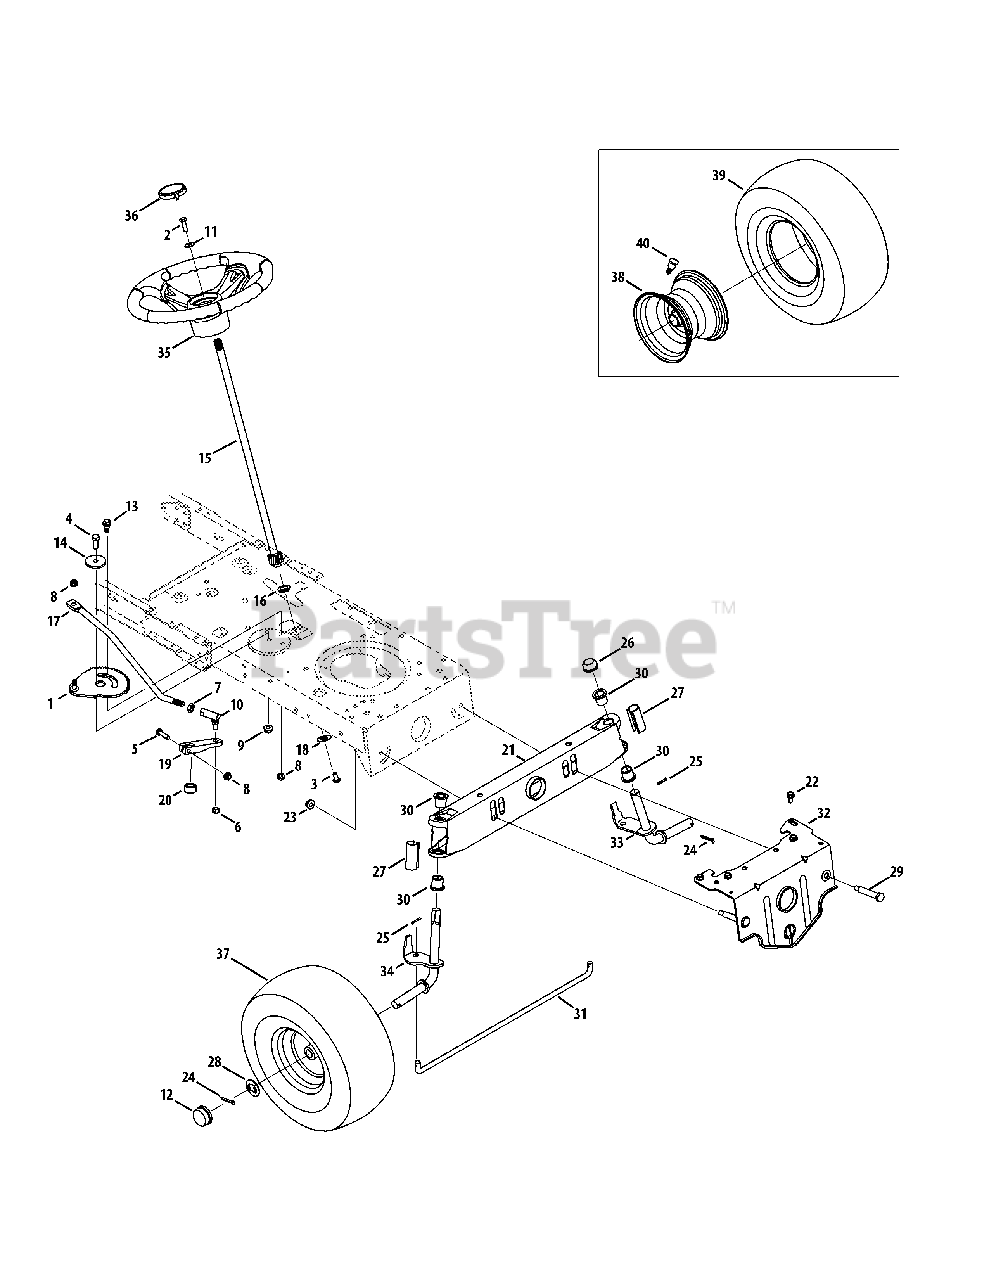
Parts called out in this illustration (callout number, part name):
1	Gear Assembly, Steering
2	Screw, 5/16-18, 1.00, Gr5, Lock
3	Screw, Mach, 5/16-18, 0.750
4	Hex Head Screw, 3/8-16 x 1.00
5	Screw, 5/16-18, 1.75, Gr5
6	Nut, Jam Lock, 3/8-24
7	Nut, Jam, 7/16-20, Gr2
8	Nut, Flange Lock, 5/16-18, Grf
9	Nut, Flange Lock, 3/8-16, Grf
10	Ball Joint, 7/16-20, Lock
11	Washer, Bell, .340 x .872 x .060
12	Hub Cap
13	Shoulder Screw, 5/16-18
14	Shoulder Spacer, .8840 x .190
15	Steering Shaft, 5/8 Spline x 21.86
16	Bearing, Flange, Hex 5/8
17	Drag Link, Steering
18	Cap, 1.25 x .16
19	Steering, Block
20	Spacer, .710 ID x .125 OD x .56
21	Pivot Bar Axle Assembly
22	Screw, 5/16-18, 0.750
23	Nut, Flange Lock, 3/8-16, GrF
24	Pin, Cotter, 5/32, 1.25
25	Pin, Cotter, 1/8 x 0.75
26	Push Cap, 3/4
27	Axle Cap
28	Washer, Flat, .781 x 1.59
29	Screw, Shlder, .500 x 2.380, 3/8-16
30	Flange Bearing
31	Tie Rod
32	Pivot Bar Bracket
33	Axle Assembly LH
34	Axle Assembly RH
35	Steering Wheel, Standard Grip
36	Cap, Steering Wheel
37	Wheel Assembly
38	Rim
39	Tire, 15 x 6 x 6 Sq. Shoulder
40	Valve Stem
